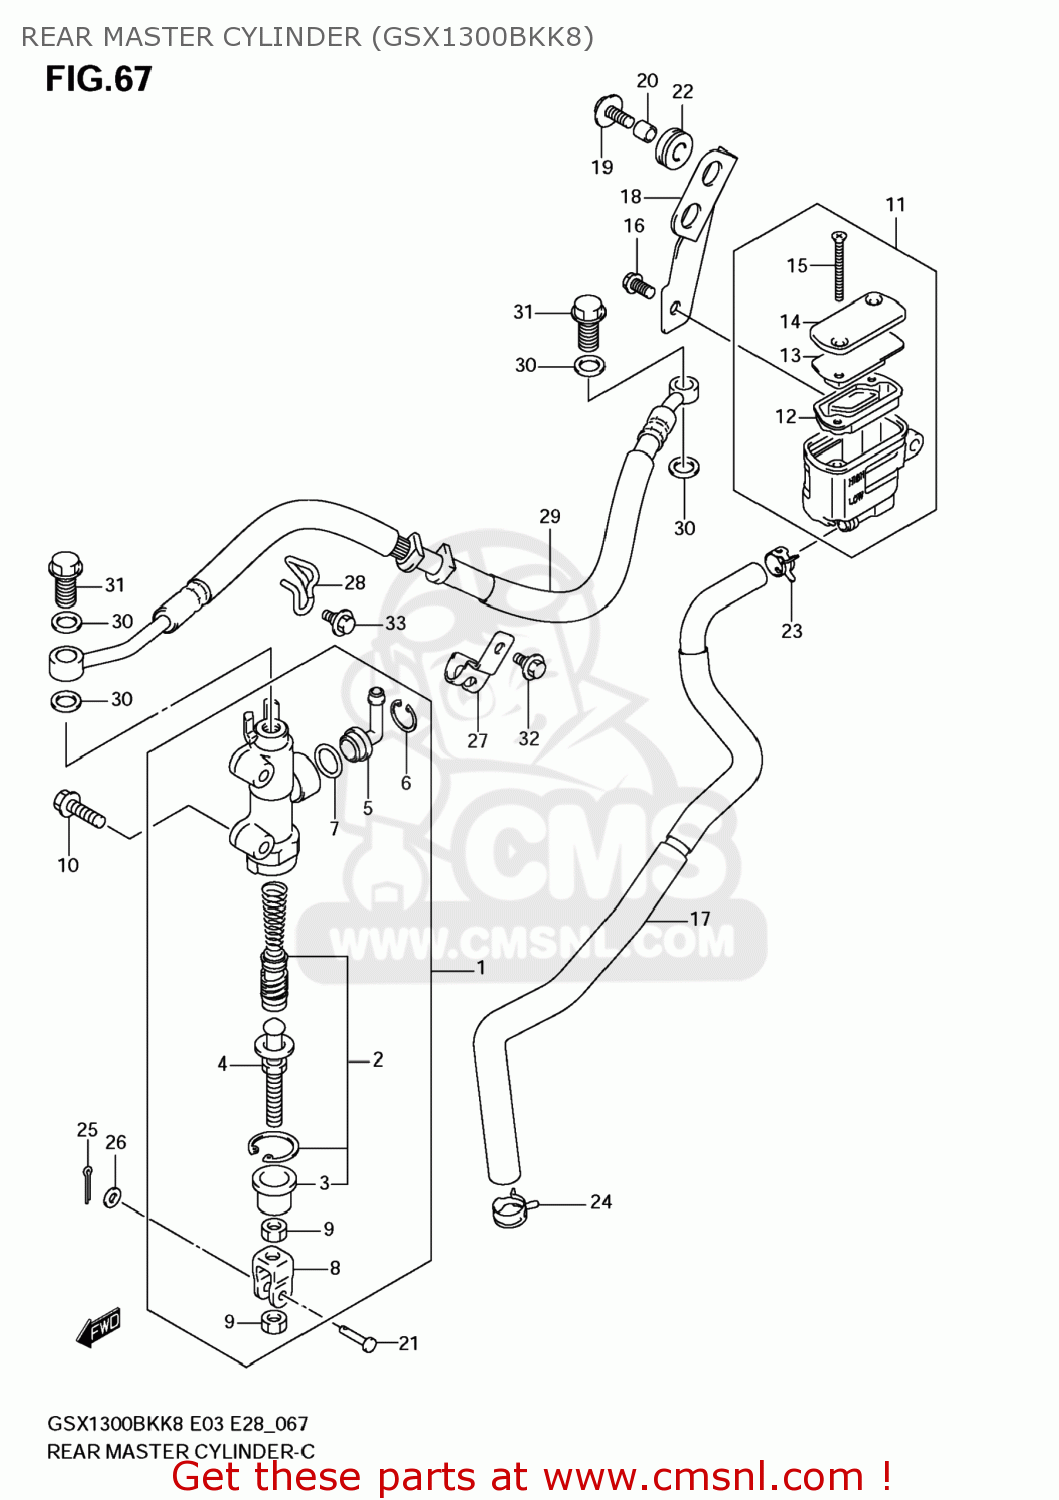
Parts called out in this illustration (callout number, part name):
1	CYLINDER ASSY,RR MASTER
2	PISTON/CUP SET
3	BOOT
4	ROD,PUSH
5	CONNECTOR
6	CIRCLIP
7	O RING
8	YOKE
9	NUT
10	SCREW(6X20)
11	TANK ASSY,RESERVOIR
12	DIAPHRAGM
13	PLATE,DIAPHRAGM
14	CAP
15	SCREW
16	BOLT
17	HOSE,RR RESERVOIR TANK
18	BRACKET,RR RESERVOIR TANK
19	BOLT(6X16)
20	SPACER(6.5X9X7.2)
21	PIN(6X18.2)
22	CUSHION
23	CLIP
24	CLIP
25	PIN
26	WASHER
27	GUIDE,RR BRAKE HOSE
28	CLAMP,RR BRAKE HOSE
29	HOSE,RR BRAKE
30	WASHER(10X15X1.5)
31	BOLT UNION
32	BOLT
33	BOLT
